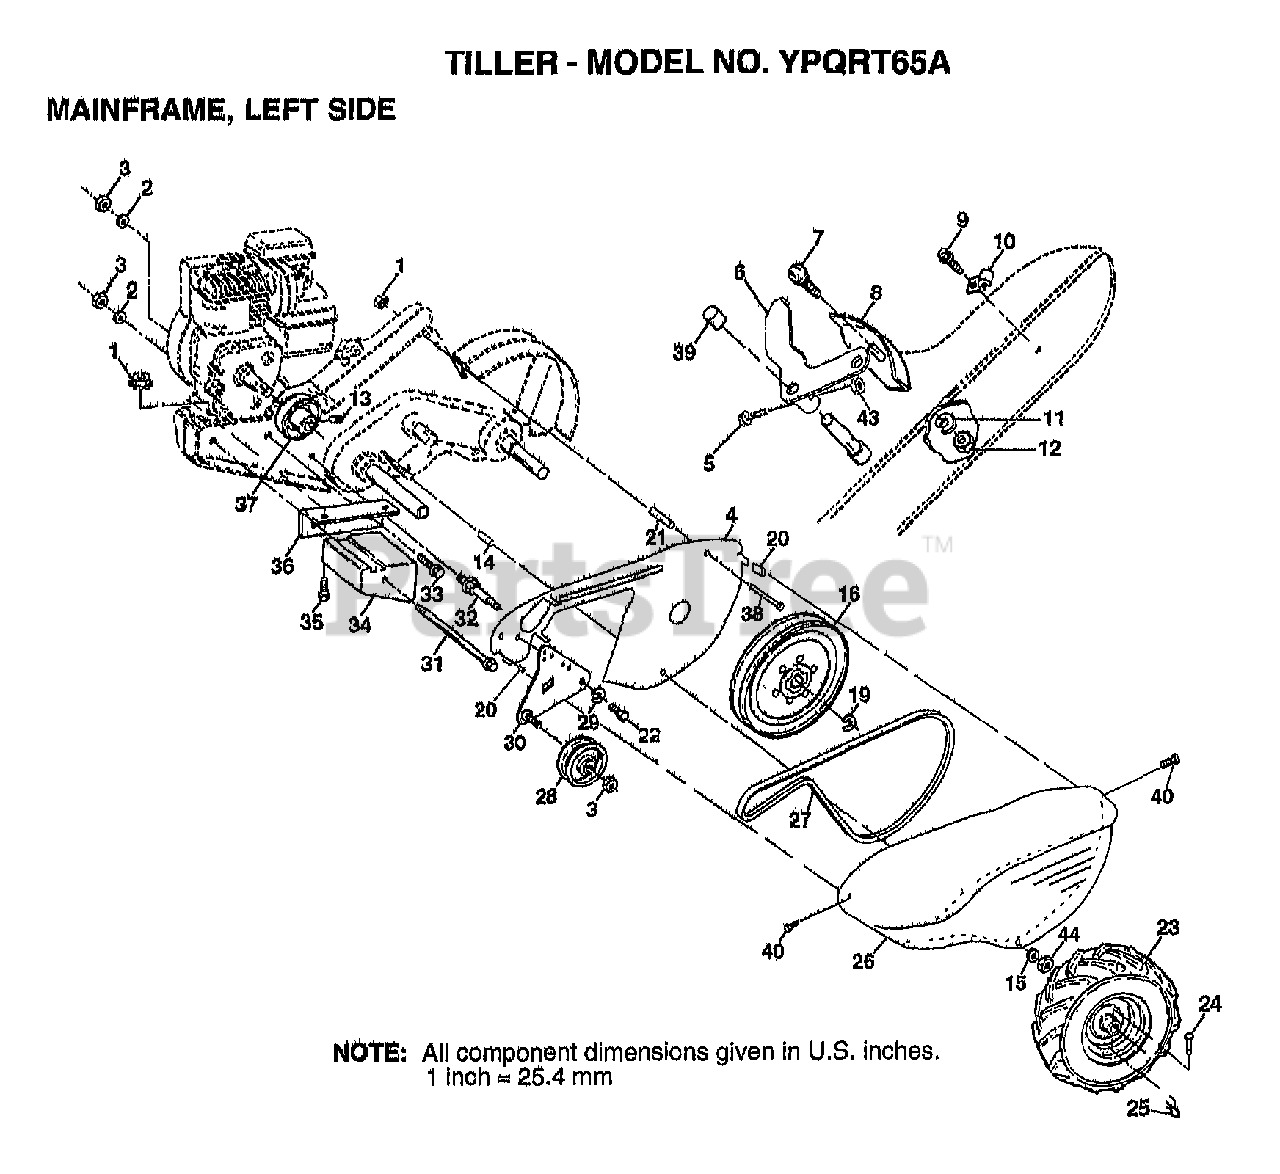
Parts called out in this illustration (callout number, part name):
2	LOCKWASHER
3	NUT.HEX.3/8-16UNC
4	SHIELD.INNER.BELT
5	"SCREW-LEVER,SHI"
6	LEVER ASM CRT
7	BOLT
8	PANEL TI
10	CONDIUT CLIP T
11	LOCKWASHER
13	SET SCREW
14	SPACER-SPLIT
15	WASHER
16	SHEAVE.TRANS.
20	NUT J CLIP #8
21	SPACER CRT
22	BOLT.FIN.HX.5/16-24X1/2
23	TIRE TI
23	RIM
24	RIVET.DRILL.1.75
25	RETAINER M
26	GUARD.BELT
27	BELT-V
28	PULLEY-IDLER TI
29	KLIP RING
30	BRACKET ASM IDLER
31	BOLT CRT
32	SHIFT ARM CRT
33	BOLT
34	COUNTERWEIGHT CRT
35	BOLT
36	BRACKET LH CRT
37	ENGINE PULLEY
39	CAP PLUNGER BLACK
40	SCREW HX WSH.HD#8-18X1/2
43	LOCKNUT
44	NUT
